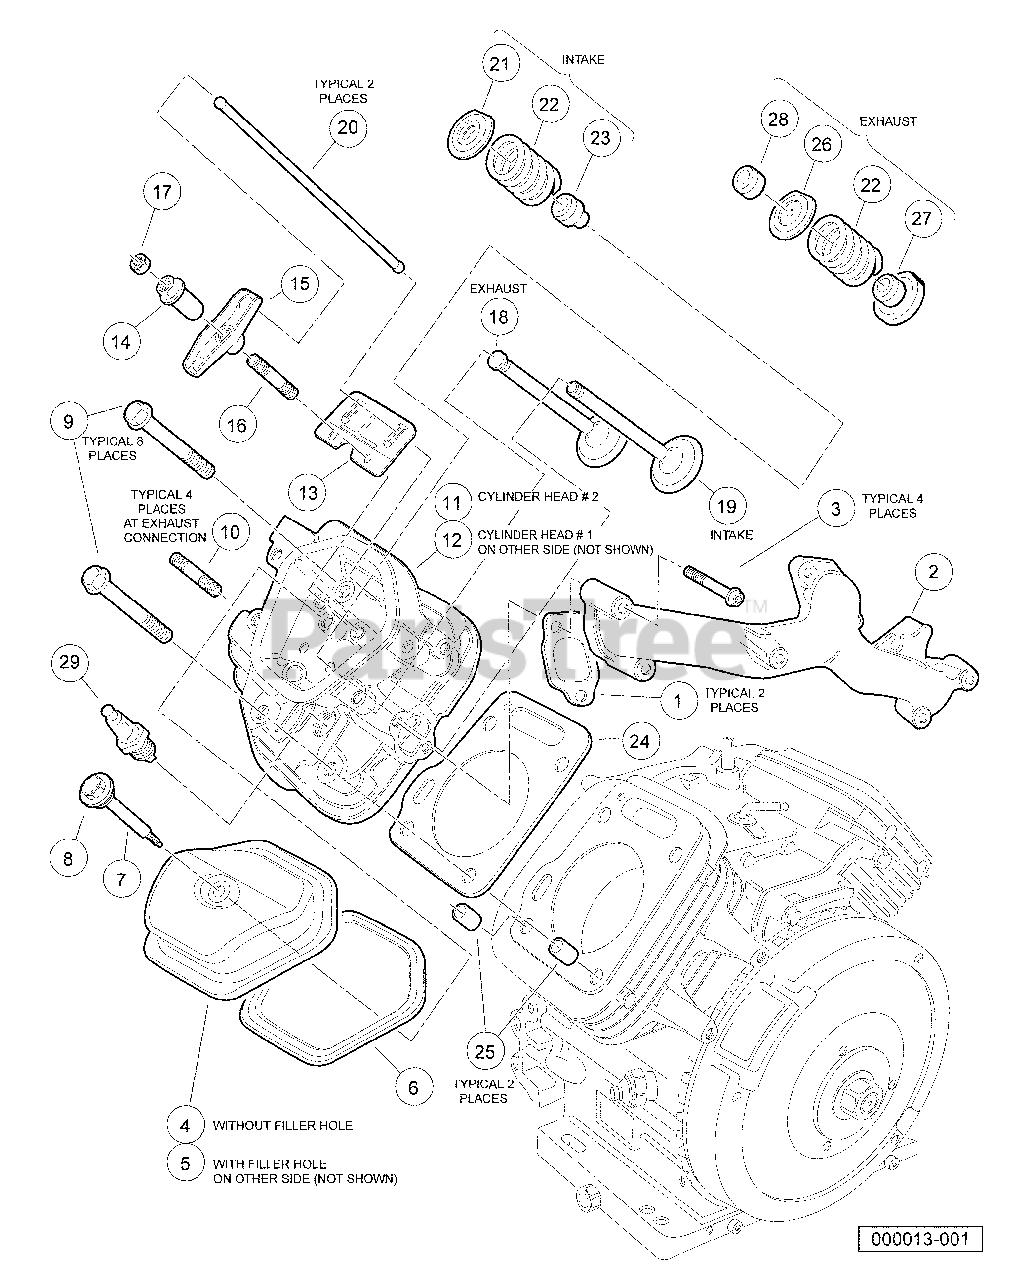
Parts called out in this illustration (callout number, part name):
1	Gasket, Intake Manifold
2	Manifold, Inlet
3	Bolt, Socket, M8 X 1.25 X 45
4	Cover, Head
5	Cover, Head Filler
6	Gasket, Cylinder Head Cover
7	Bolt, Head Cover
8	Washer, Head Cover
9	Bolt, Flange Head, M10 X 1.5 X 80
10	Bolt, Stud, M8x22
11	Cylinder Head, #2
12	Cylinder Head, #1
13	Plate, Push Rod Guide
14	Pivot, Rocker Arm
15	Arm, Valve Rocker
16	Bolt, Pivot, M8
17	Nut, Pivot Adj
21	Retainer, In Valve Spring
22	Spring, Valve
23	Seal, Valve Stem
24	Gasket, Cylinder Head
25	Pin A, Dowel ,12 X 20
26	Retainer, Ex Valve Spring
27	Seat, Valve Spring
28	Rotator, Valve
29	Spark Plug, BPR2ES
